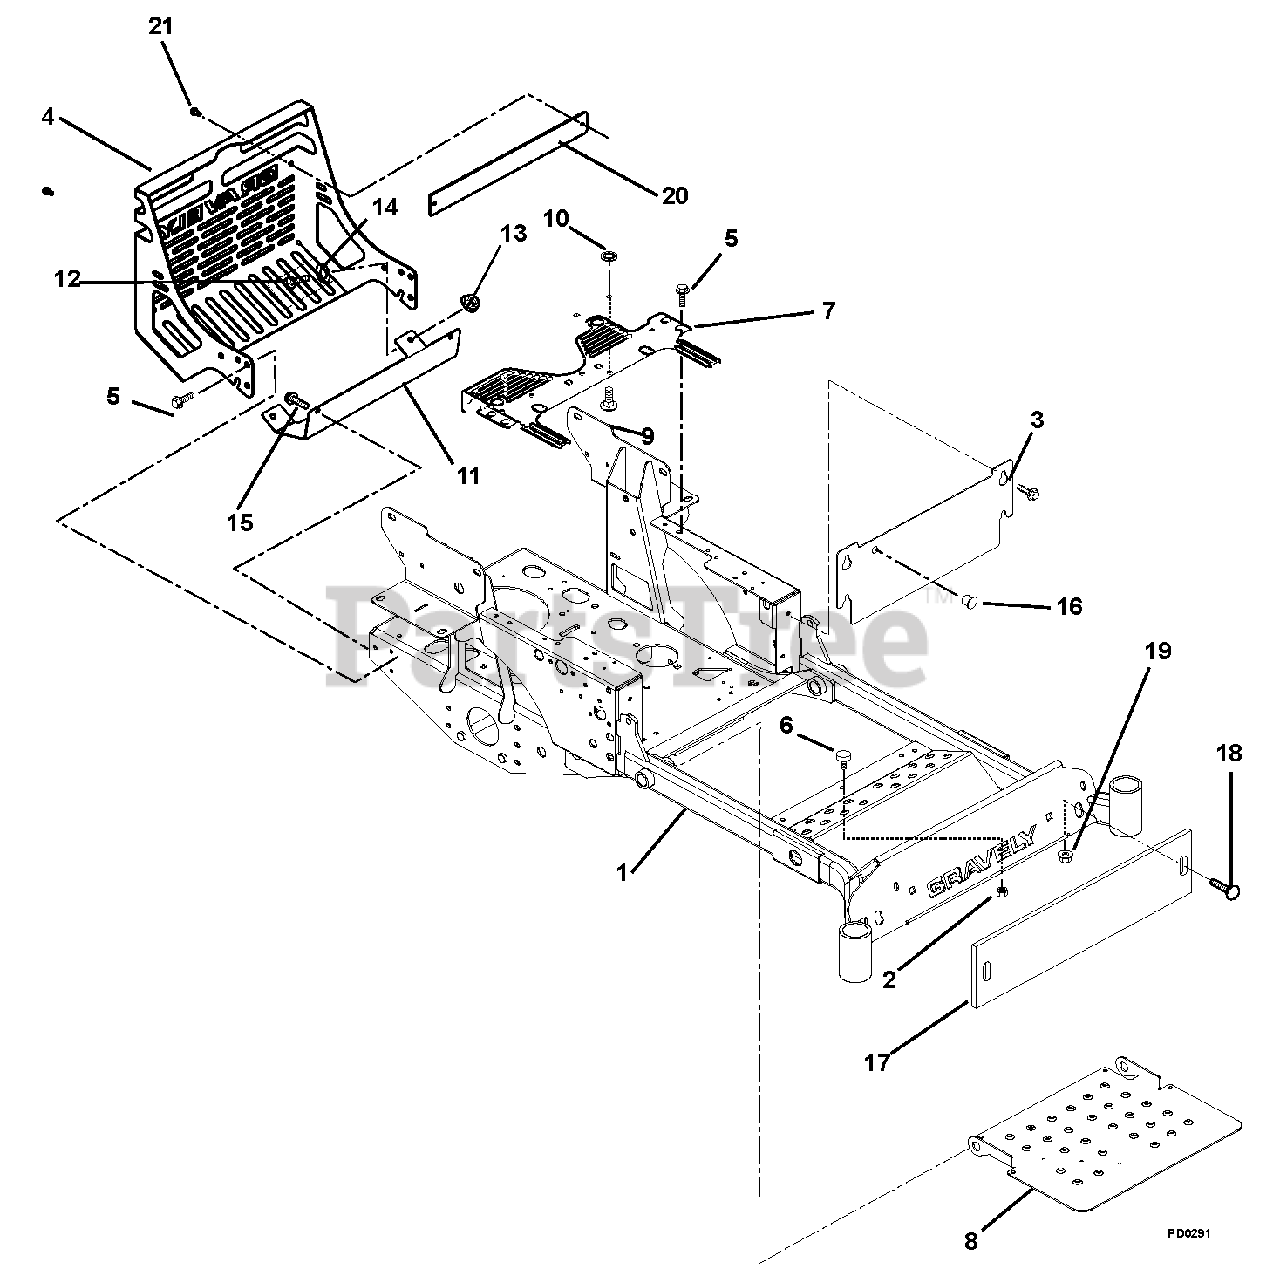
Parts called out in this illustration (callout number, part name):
1	Frame, Compact-Z
2	Nut, Spin Lock Flange .312-18
3	Access Panel
4	Bumper, Rear
5	Screw, Tapping .38-16 x .75 Hex Washer Head
6	Bumper, Rubber
7	Seat Support
8	Panel, Inspection
9	Bolt, Round Head Square Short Neck .31-18 x .75 Grade 5
10	Nut, Push .312
11	Heat Shield, Compact Z
12	Bolt, Hex .38-16 x .75 Grade 5
13	Nut, Nyloc Flange .38-16
14	Washer, Flat Steel .438 x 1.00 x .083
15	Screw, Tapping .38-16 x .50 Hex Washer Head
16	Plug, Hole .56
17	Counterwieght CZ Front- Black
18	Bolt, Round Head Square Neck .50-13 x 2.50 Grade 5
19	Nut .50-13 Nyloc Flange
20	Plate, Bumper
21	Screw, Tapping .25-20 x .50 Hex Washer Head
